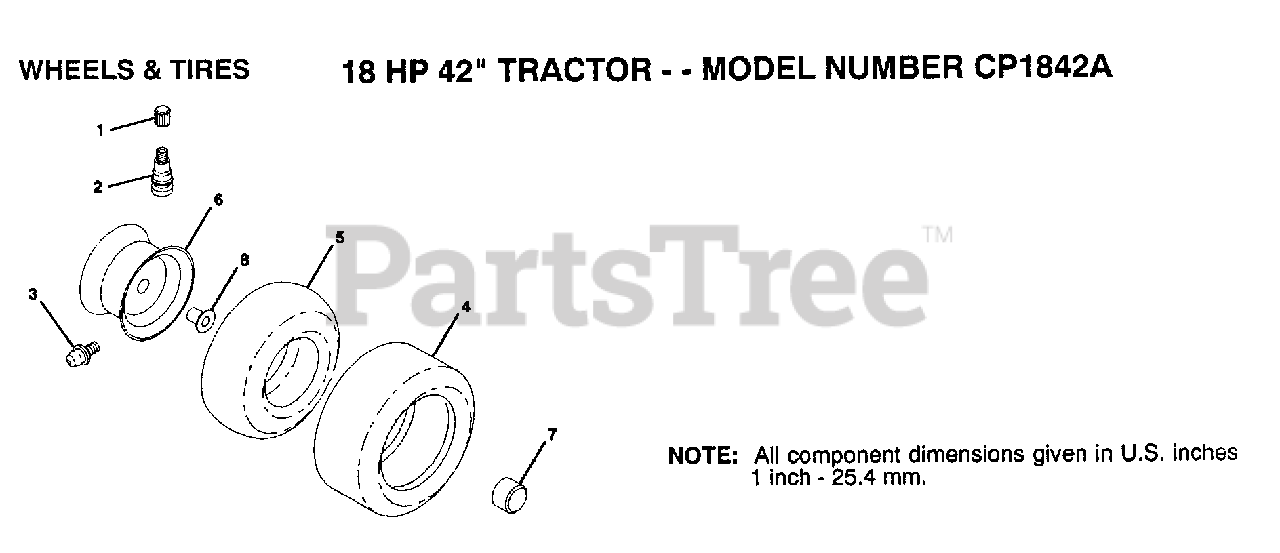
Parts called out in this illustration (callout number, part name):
1	VALVE CAP
2	VALVE STEM LT
3	FITTING LT
4	TIRE TM 15X6X6
4	TIRE TM 20X8X8
5	TUBE.5.3/4.5/6
5	TUBE.18X9.5-8
7	HUB CAP
8	"FLANGE, BEARING"
